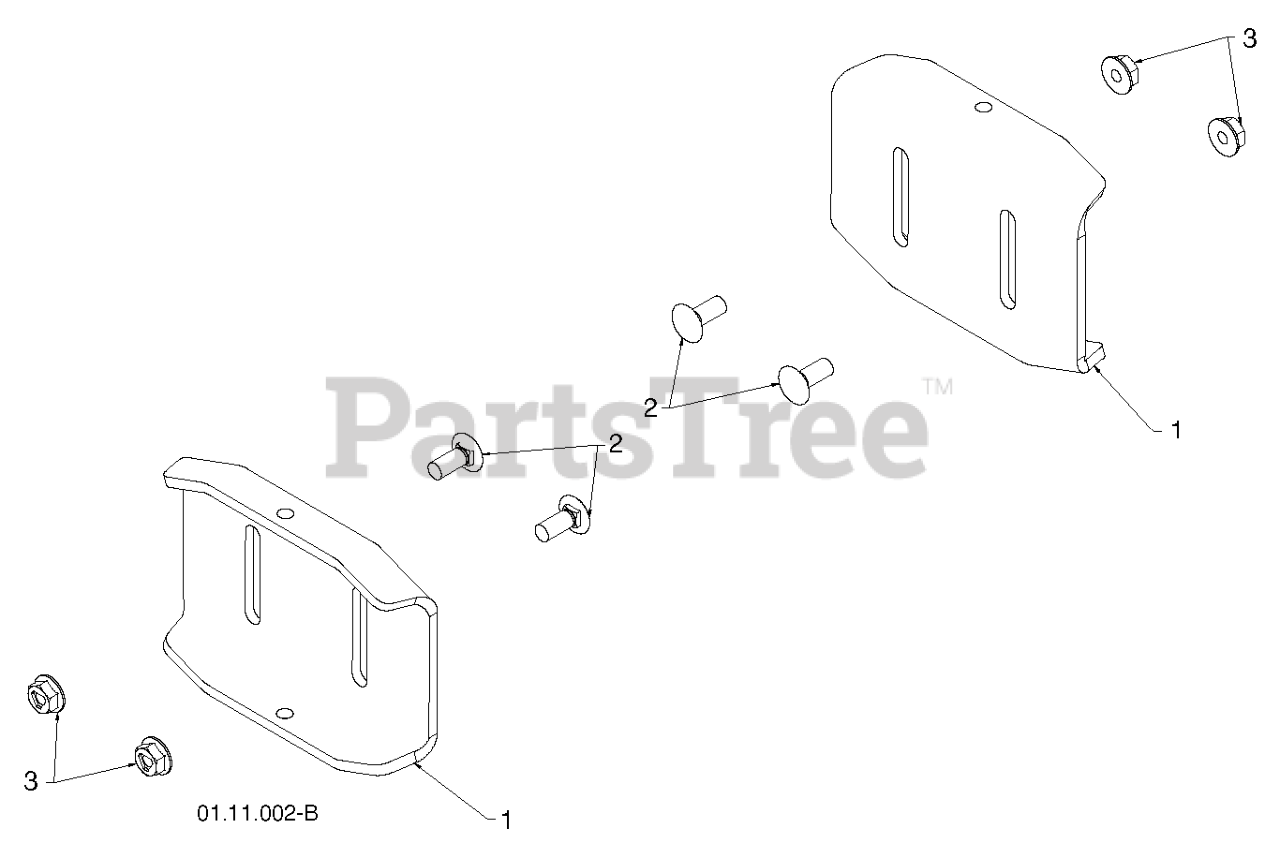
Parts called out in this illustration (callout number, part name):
1	SKID PLATE
2	BOLT
3	NUT.LOCK.5/16-18
